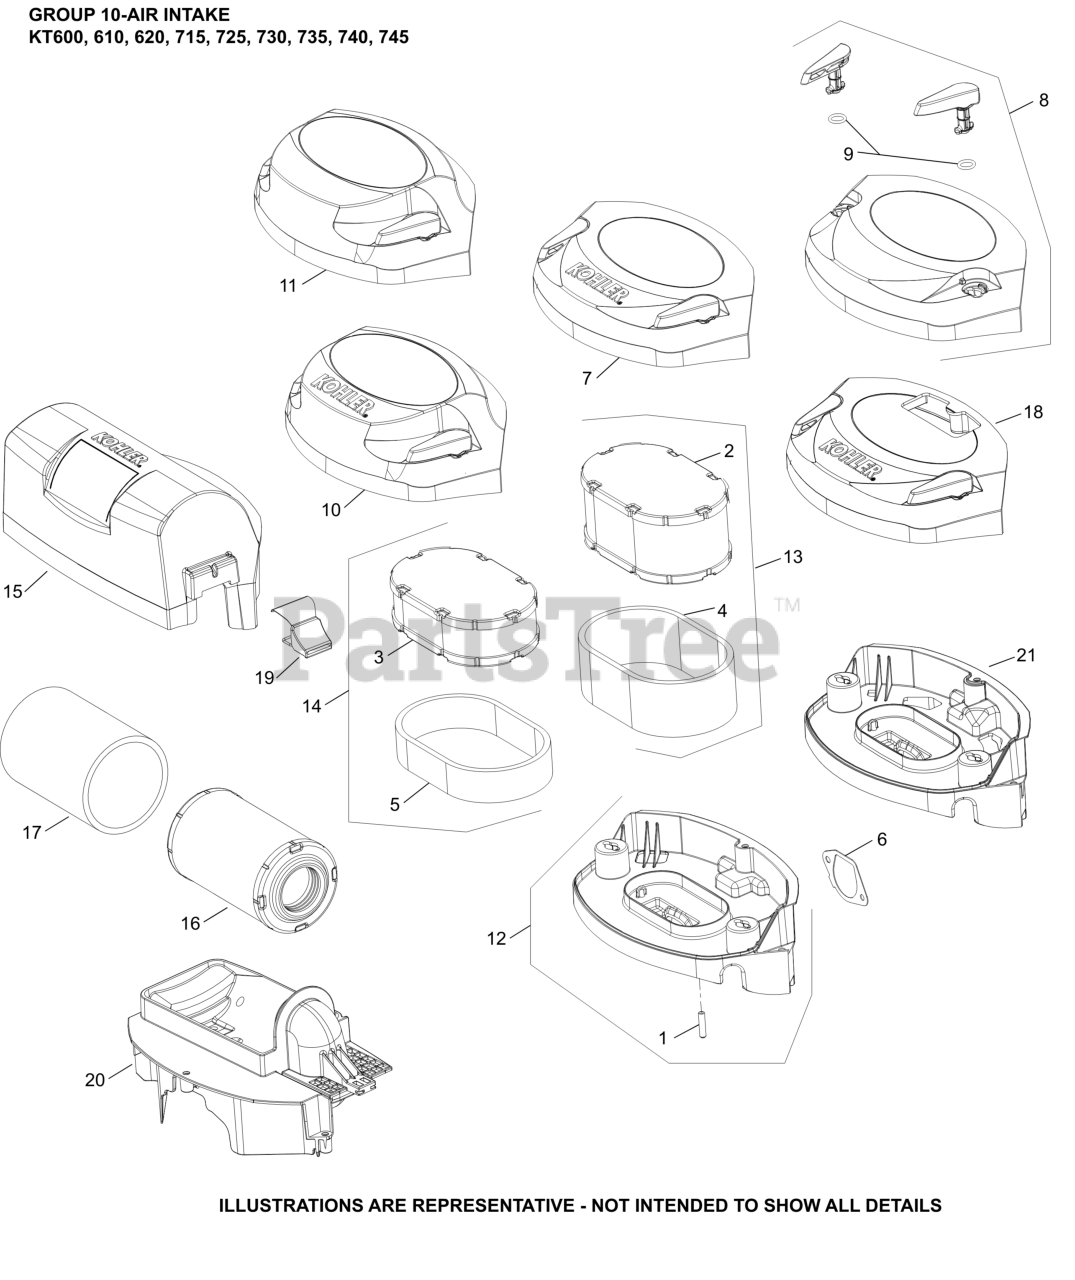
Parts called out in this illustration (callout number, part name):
1	CAP, MASKING
2	ELEMENT, AIR FILTER
4	ELEMENT, PRE-CLEANER
6	GASKET, AIR CLEANER BASE
10	COVER ASSY, AIR CLEANER
21	BASE ASSEMBLY, AIR CLEANER
NI	FITTING, FUEL SYSTEM
